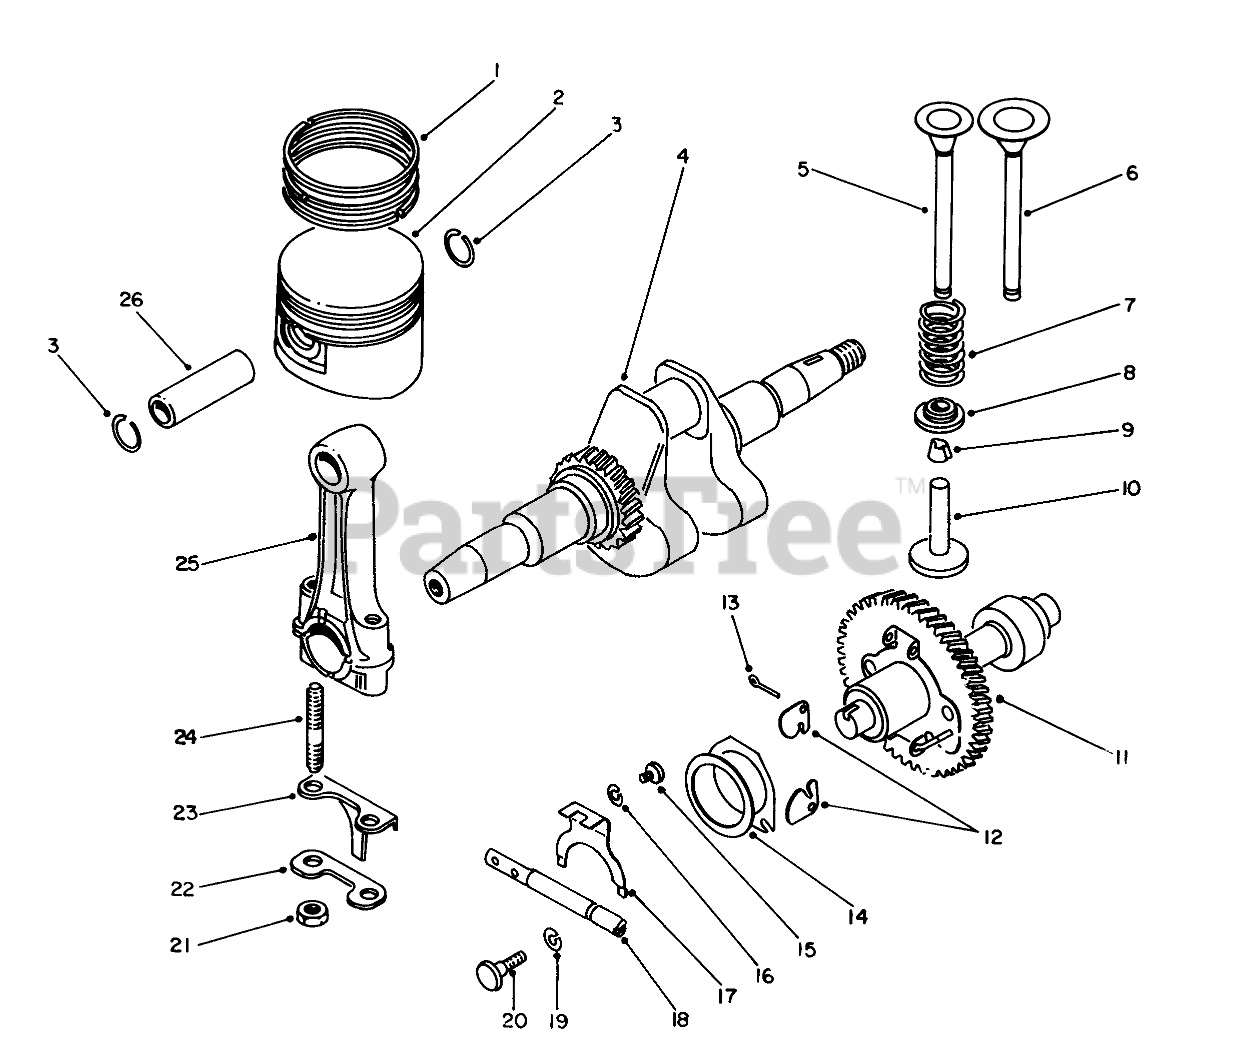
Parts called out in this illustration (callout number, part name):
1	RING SET
2	Piston
3	Circlip
4	Crankshaft
5	EXHAUST VALVE
6	Valve-Intake
7	Spring
8	Retainer
9	Cotter
10	Tappet
11	Camshaft
13	Cotter Pin
14	Spacer
15	Screw
16	Lockwasher
17	PLATE
18	Shaft
19	Gasket
20	Screw
22	LOCK PLATE
23	Plate-Splash
25	Rod-Connecting (Incl. Ref. #21-24)
26	PISTON PIN
